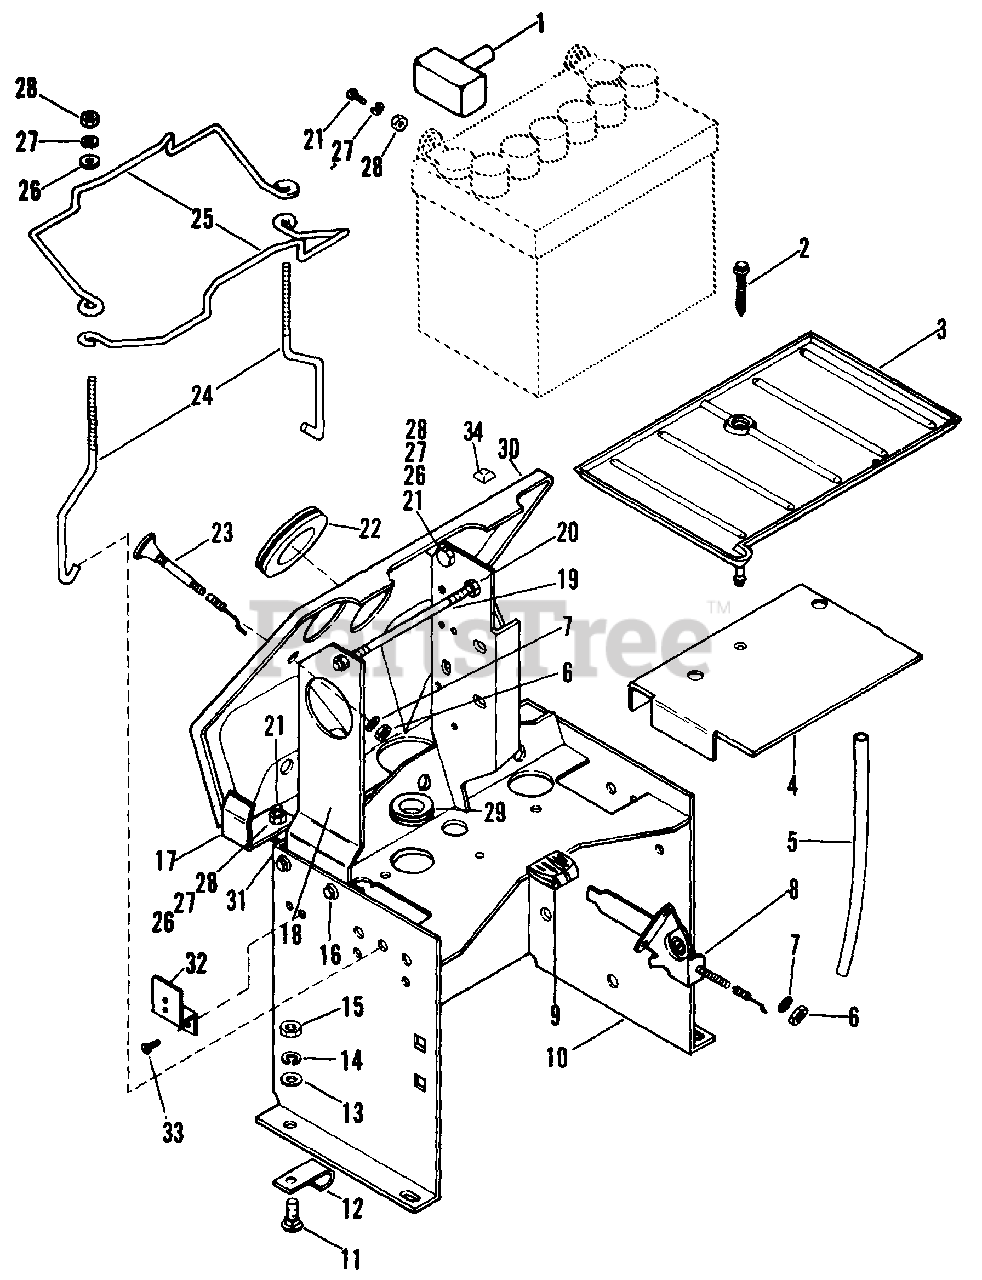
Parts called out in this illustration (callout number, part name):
1	Insulator
2	Screw, Tapping #12-14 x 1.50 OVHPL
3	Battery Tray
4	Battery Stand
5	Hose, Drain
6	Nut, #10-24 Hex
7	Washer, Lock No. 10 SP
8	Throttle Control
9	Knob
10	Dash Support
11	Bolt, Carriage 5/16-18 x .75
12	Clip
13	Washer, Flat .375 x .734 x .065
14	Washer, Lock 5/16 SP
15	Nut, Hex 5/16-18
16	Taptite, 1/4-20 x .50
17	Clip
18	Hourmeter Mounting Plate
19	Brace Rod
20	Nut, Lock 1/4-20
21	Bolt, Hex 1/4-20 x .875
22	Grommet
23	Choke Control
24	Tie Down
25	Hold Down
26	Washer, Flat .281 x .625 x .065
27	Washer, Lock 1/4 Reg.
28	Nut, Hex 1/4-20
29	Grommet
30	Dash
31	Screw, Tapping #10-16 x .50 HWHPL
32	Bracket, Hood Latch Mtg.
33	Screw, Tapping #8-15 x .375 R.H.
34	Stop
NS	Instruction Decal
NS	Rear Implement Decal
NS	Decal, Danger
